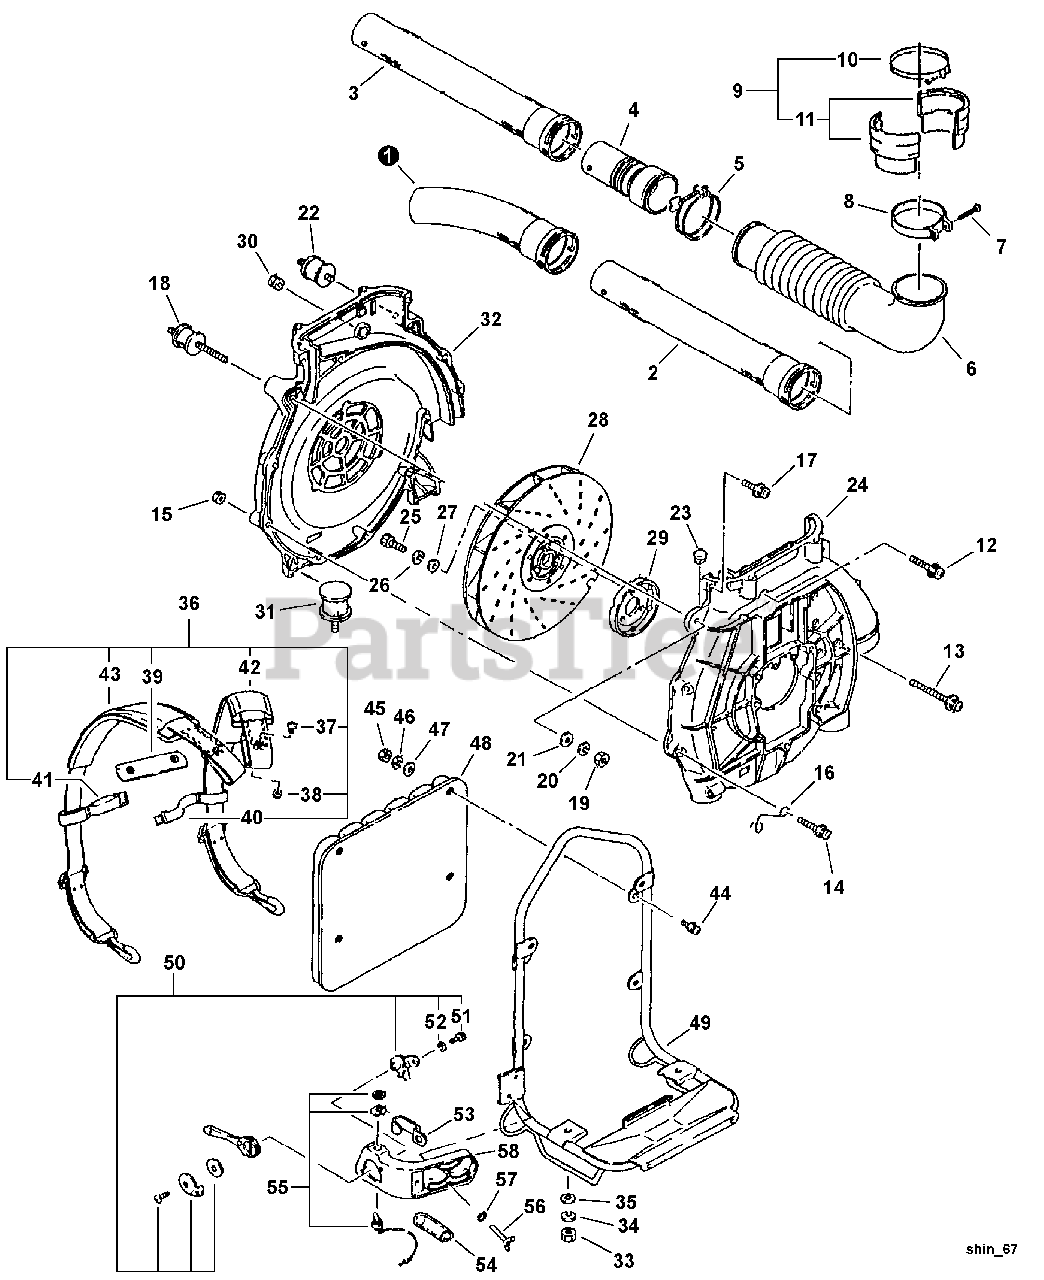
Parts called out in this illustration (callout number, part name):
1	TUBE, BLOWER - CURVED
2	TUBE, BLOWER - STRAIGHT
3	TUBE, BLOWER - STRAIGHT
4	JOINT, BLOWER TUBE
5	CLAMP - B
6	TUBE, BLOWER - FLEXIBLE
7	CLAMP KIT
8	CLAMP KIT
9	JOINT ASSY
11	SWIVEL JOINT KIT
12	SCREW - 5×45
13	SCREW - 5×80
14	SCREW - 5×45
15	NUT M5
16	CABLE CLIP
17	SCREW M5×30
18	CUSHION
19	NUT M5
20	WASHER, SPRING 5
21	WASHER
23	GROMMET
24	COVER, FAN - OUTER
25	BOLT 6×25
26	WASHER, SPRING 6
27	WASHER 6.5×11.5×0.8
28	FAN
29	DEFLECTOR, AIR
30	GROMMET A
32	COVER, FAN - INNER
33	NUT, HEX M6
34	WASHER, SPRING 6
35	WASHER
36	HARNESS ASSY
37	SCREW - 6×16
38	NUT, LOCK M6
39	CONNECTOR, STRAP
40	BAND - RIGHT
41	BAND - LEFT
42	STRAP
43	STRAP
44	SCREW M5×10
45	NUT M5
46	WASHER, SPRING 5
47	WASHER
48	PAD
49	FRAME, BACKPACK
50	THROTTLE LEVER ASSY
51	SCREW - 6×10
52	WASHER, SPRING 6
53	CLAMP, WIRE
54	TUBE
55	SWITCH, ON-OFF
56	THUMBSCREW
57	WASHER, TOOTH
58	BRACKET
